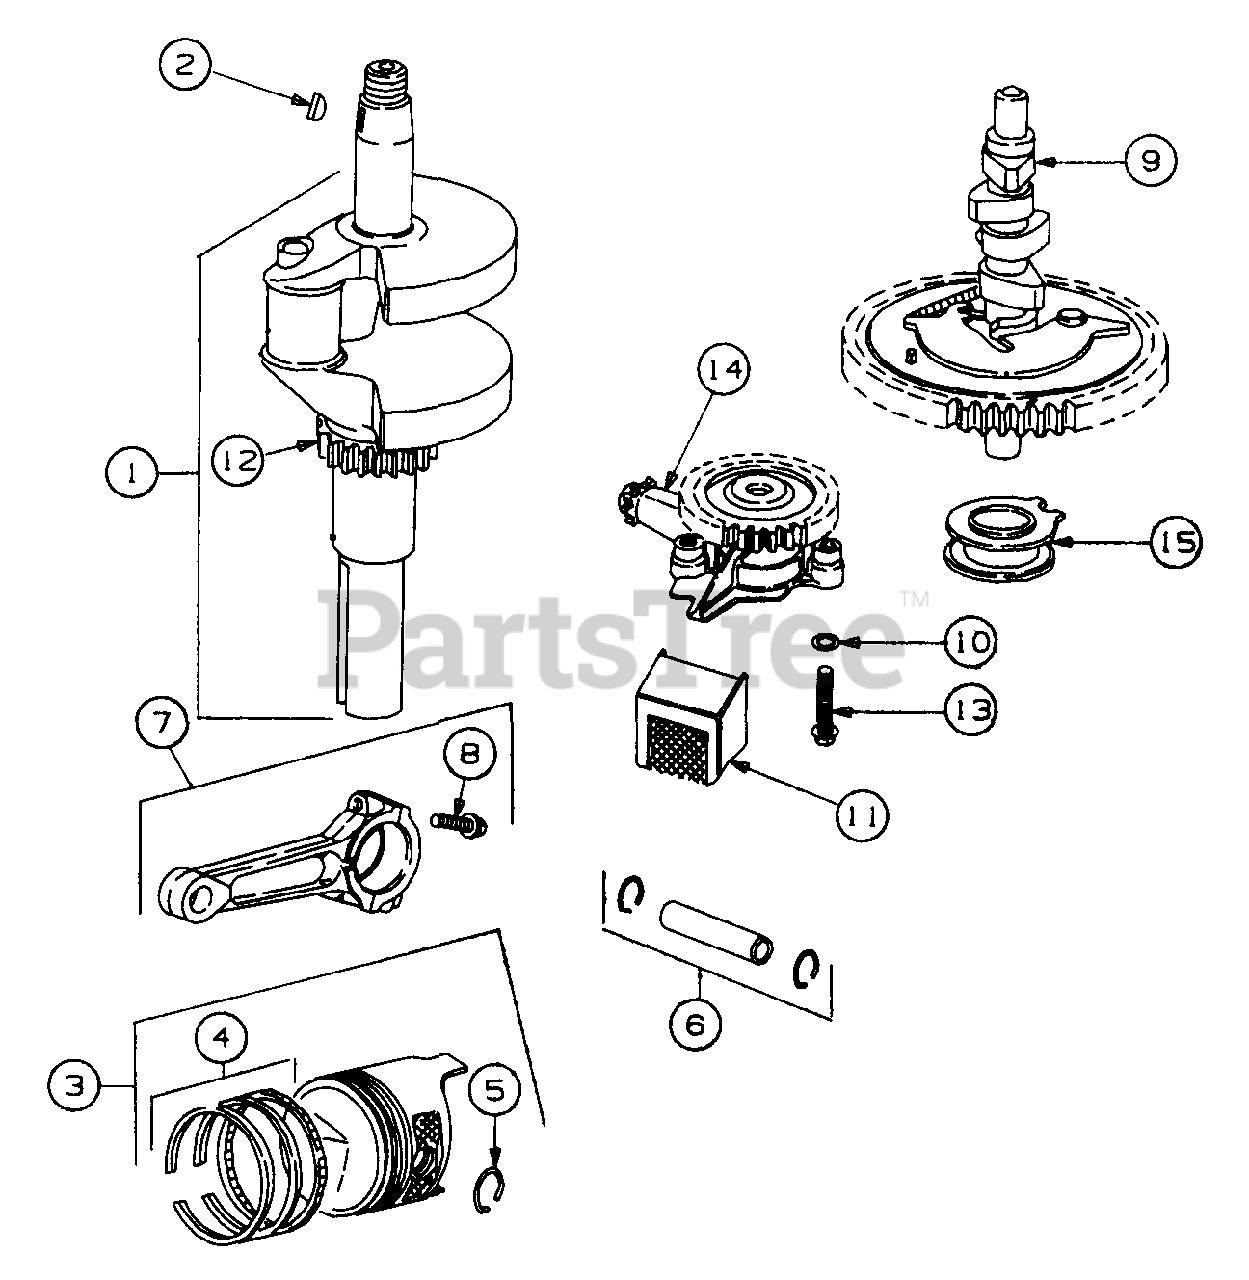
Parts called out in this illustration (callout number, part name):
1	Crankshaft
2	Key, Flywheel
3	Piston Assy (Standard)
4	Ring Set, Piston (Standard)
5	Lock, Piston Pin
6	Pin Assy, Piston (Standard)
7	Rod Assy, Connecting
8	Screw, Connecting Rod
9	Gear, Cam
10	O-Ring (Oil pump)
11	Screen, Oil
12	Gear, Timing
13	Screw, Sem
14	Oil Pump Assy
15	Slider, Governor
